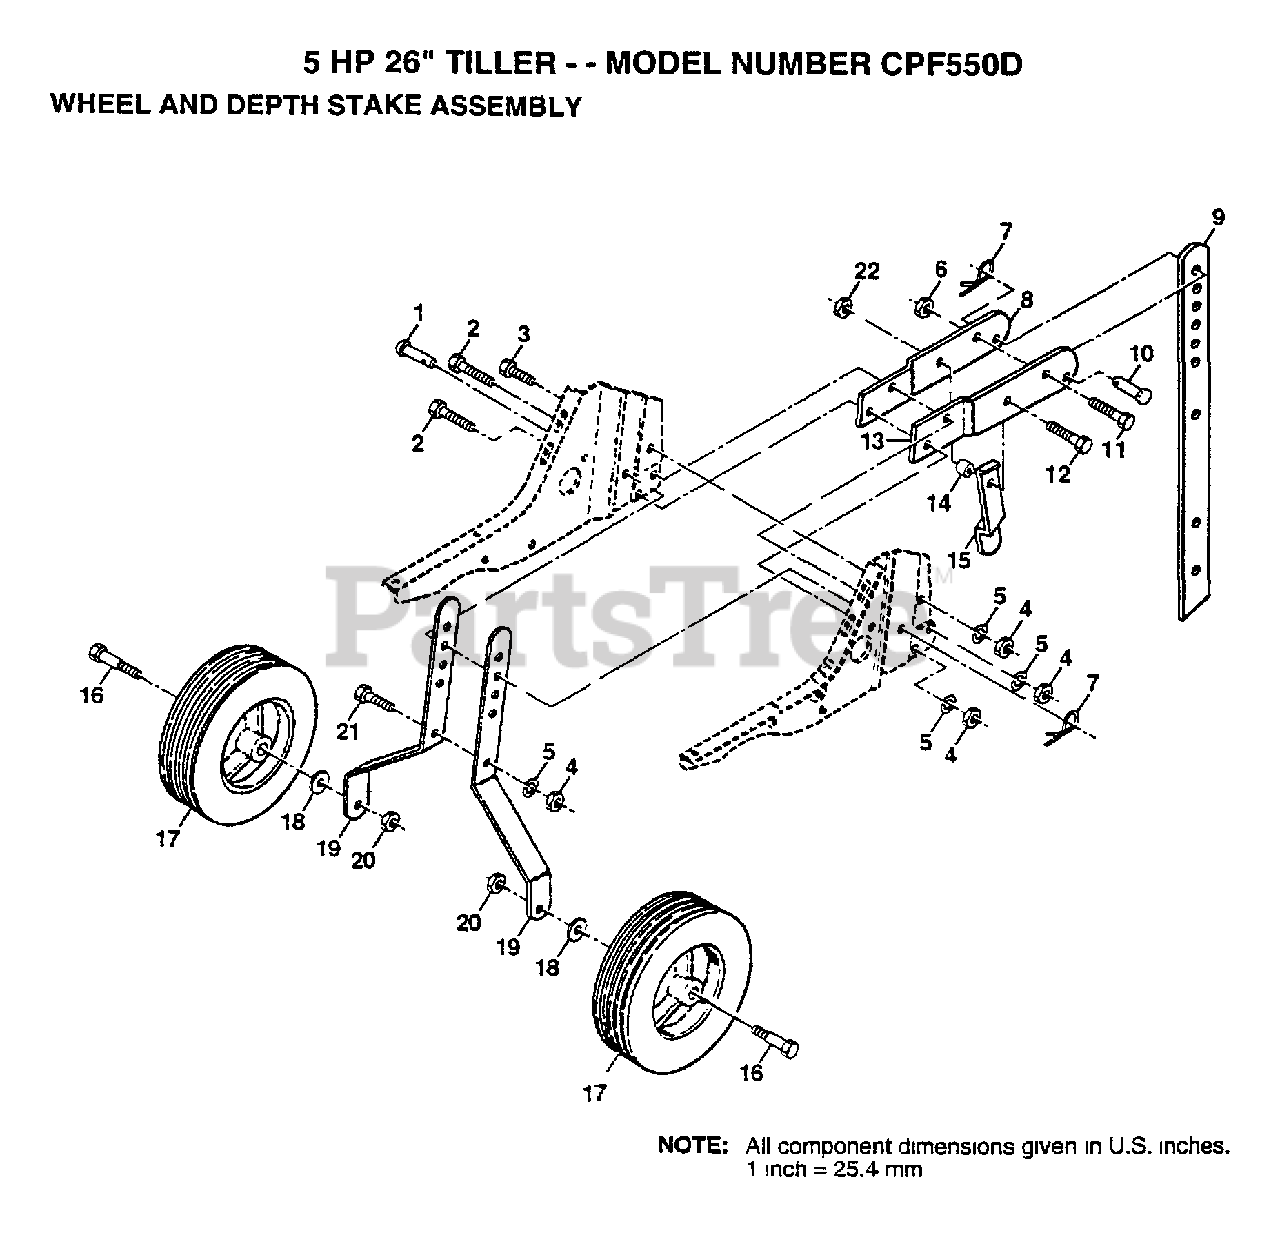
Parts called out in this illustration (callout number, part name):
1	DRILLED RIVET RT
3	BOLT
4	NUT.HEX.5/16-18
5	LOCKWASHER
6	NUT
7	SPRING.RETAINER
8	SUPPORT STAKE RH
11	BOLT
12	BOLT.HEX.5/16-1.5
13	SUPPORT STAKE LH
14	WASHER
15	STAKE SPRING TI
16	BOLT SHOULDER
18	WASHER
19	BRACKET.WHL.PNT.
22	NUT
